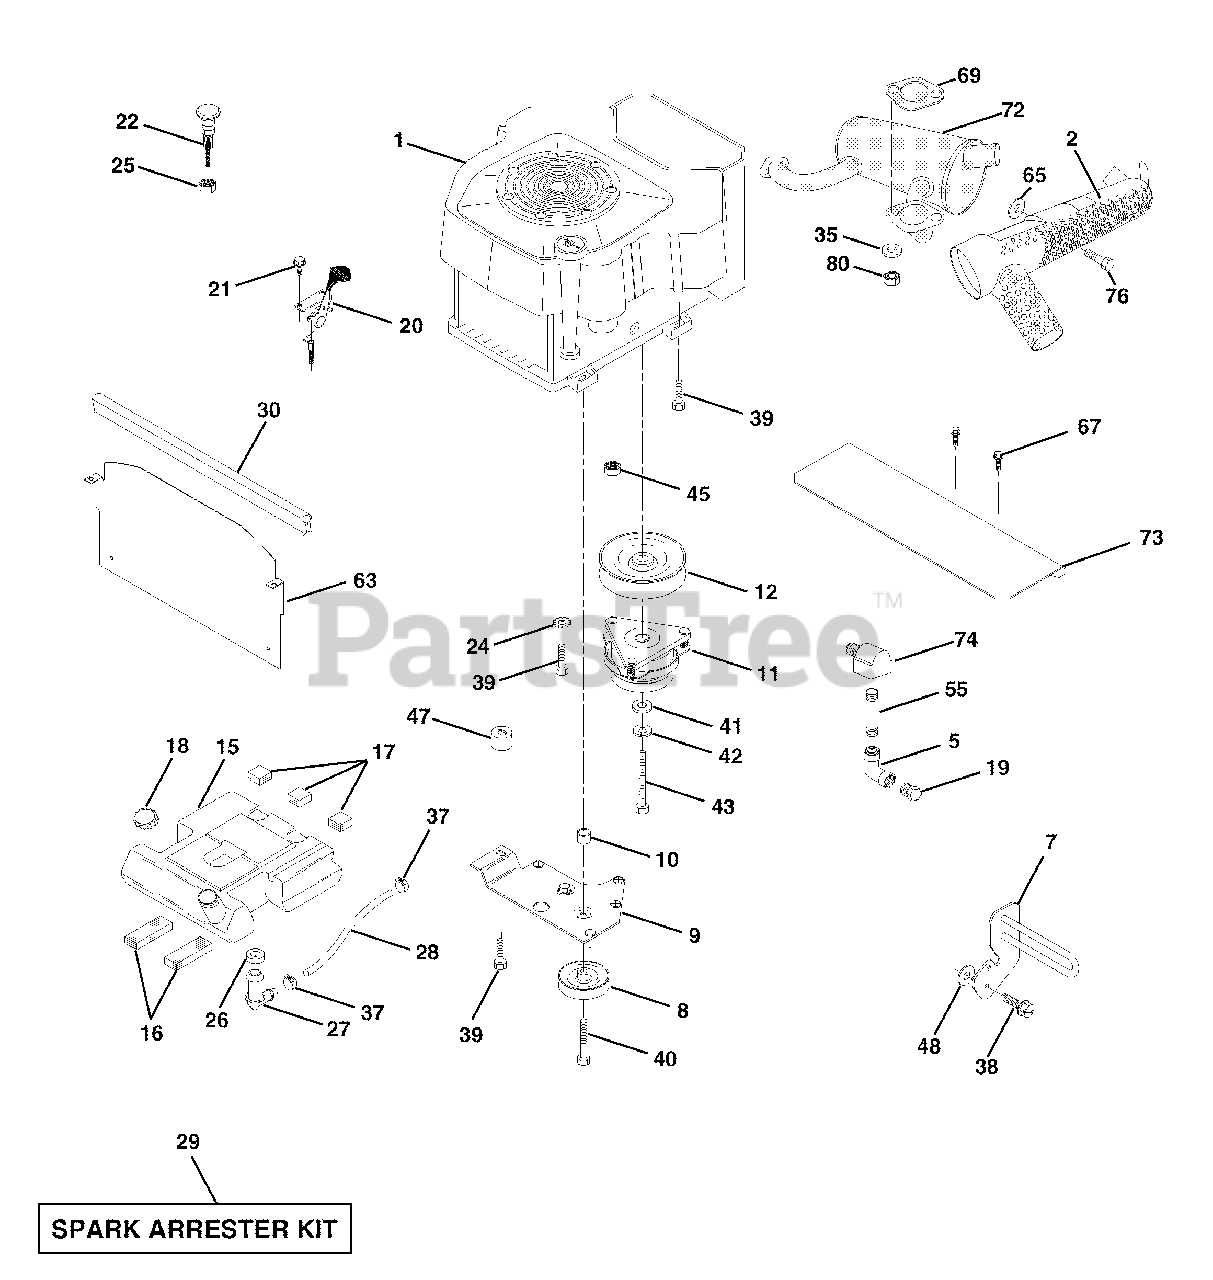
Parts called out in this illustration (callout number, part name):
2	Muffler VGT Side Mount
5	Elbow STD 90 Degree 3/8 - 18 NPT
7	Muffler Assembly Guard
8	Pulley V-Idler
9	Keeper Asm. Belt Engine VGT
10	Bushing
11	Clutch Electric
12	Pulley Engine VGT Elect Clutch
15	Tank Fuel Rear 3.50
16	Pad Spacer
17	Pad Spacer
18	Cap Asm Fuel W/Sym Vented
19	Plug Oil Drain
20	Control Throttle
21	Screw Hex Thd Cut 1/4 - 20 X 5/8
22	Control Choke
24	Washer Ext Tooth 3/8
25	Nut Keps 3/8-24 Unf
26	Bushing
27	Stem Tank Fuel
29	Spark Arrester Kit
30	Extrusion Hood
35	Washer
37	Clamp Hose
38	Screw 3/8-16 x 1-1/4
39	Screw TT 3/8-16 x 2-1/4 UNC
40	Screw TT 3/8-16 x 4 UNC
41	Washer 1-1/2 OD X 15/32 ID X .250
42	Washer Lock 7/16
43	Bolt Hex 7/16-20 X 4-1/4 Ga 5
47	Spacer Engine CV22 Round PM
48	Washer 13/32 x 1-1/4 x 7 Ga.
55	Nipple, Pipe 4-1/2
63	Shield, at VGT 22 HP YP/Husq.
65	Washer 13/32 x 1 x 14 Ga.
67	Screw 5/16-18 x 3/4
69	Gasket
72	Muffler VGT
73	Heat Shield Kohler 25
74	Elbow Street Brass
80	Nut Flange M8-1.25 Non-Lk. Zinc
